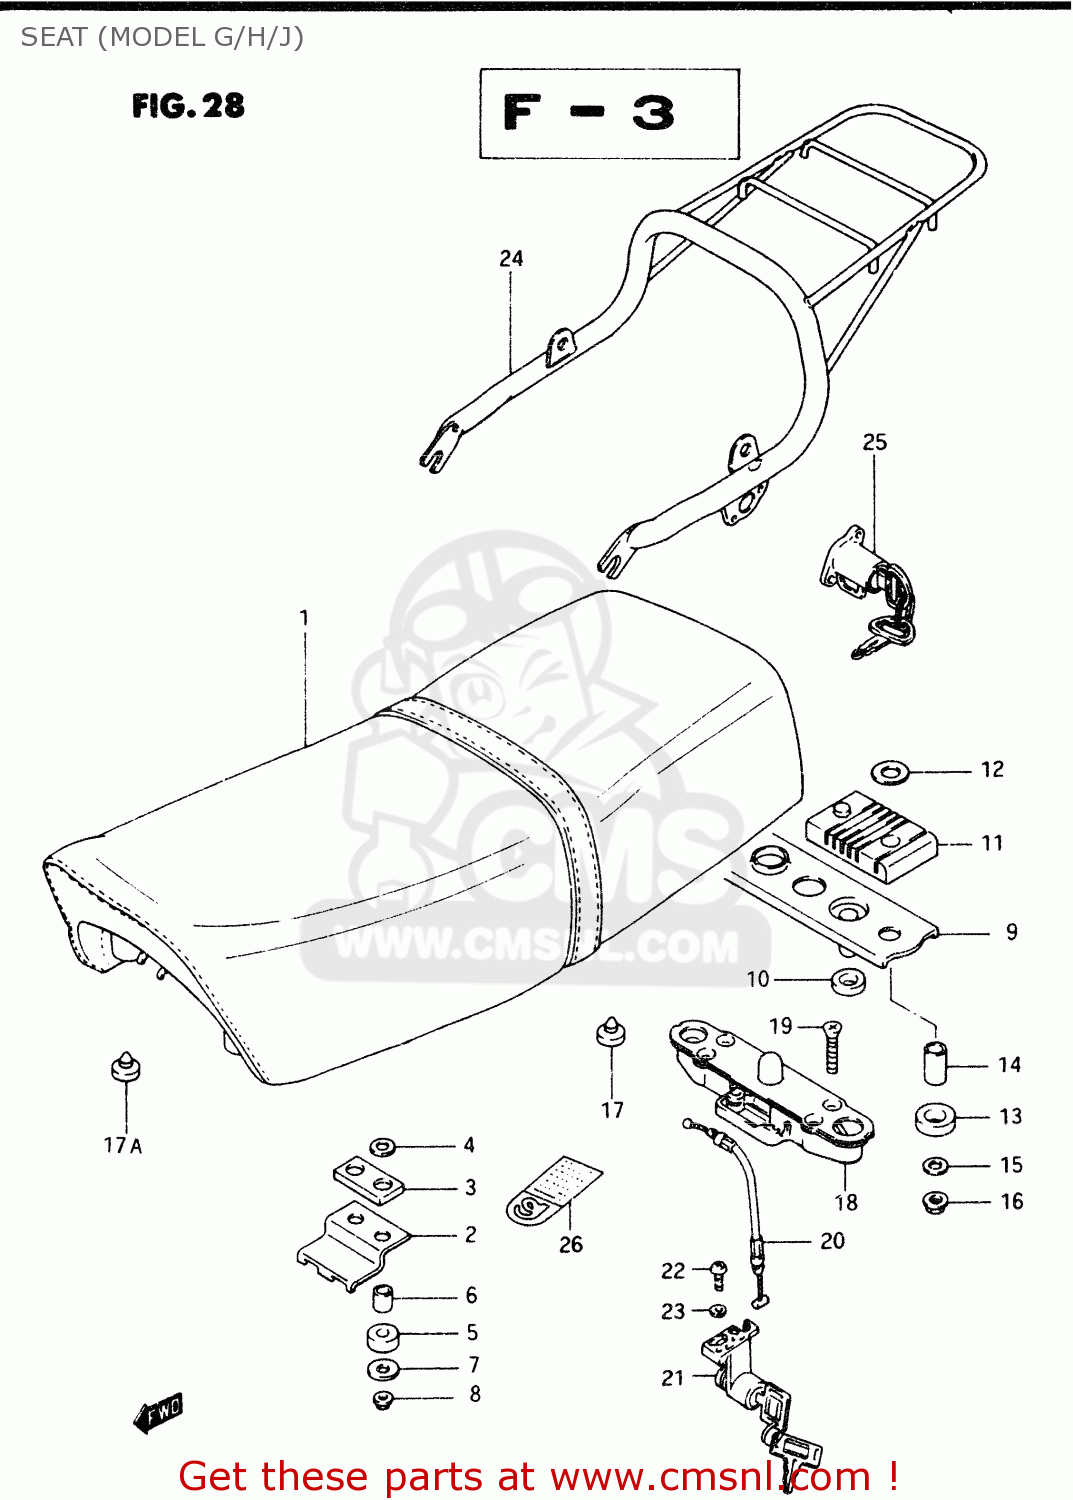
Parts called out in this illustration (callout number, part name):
1	SEAT SET (BLUE)
2	PLATE,SEAT HOOK FR
3	CUSHION,SEAT
4	WASHER
5	CUSHION
6	SPACER (6.1X8X12)
7	WASHER
8	NUT
9	PLATE,SEAT LOCK STRIKER
10	CUSHION
11	CUSHION, UPPER
12	WASHER
13	CUSHION,SEAT FR
14	SPACER,SEAT SUPPORT
15	WASHER
16	NUT
17	CUSHION
17A	CUSHION
18	LOCK ASSY,SEAT STRIKER
19	SCREW,6X30
20	CABLE,SEAT LOCK
21	LOCK SET,SEAT
22	SCREW
23	LOCK WASHER
24	CARRIER
25	LOCK SET,HELMET
26	LABEL,ASBESTOS WARNING
